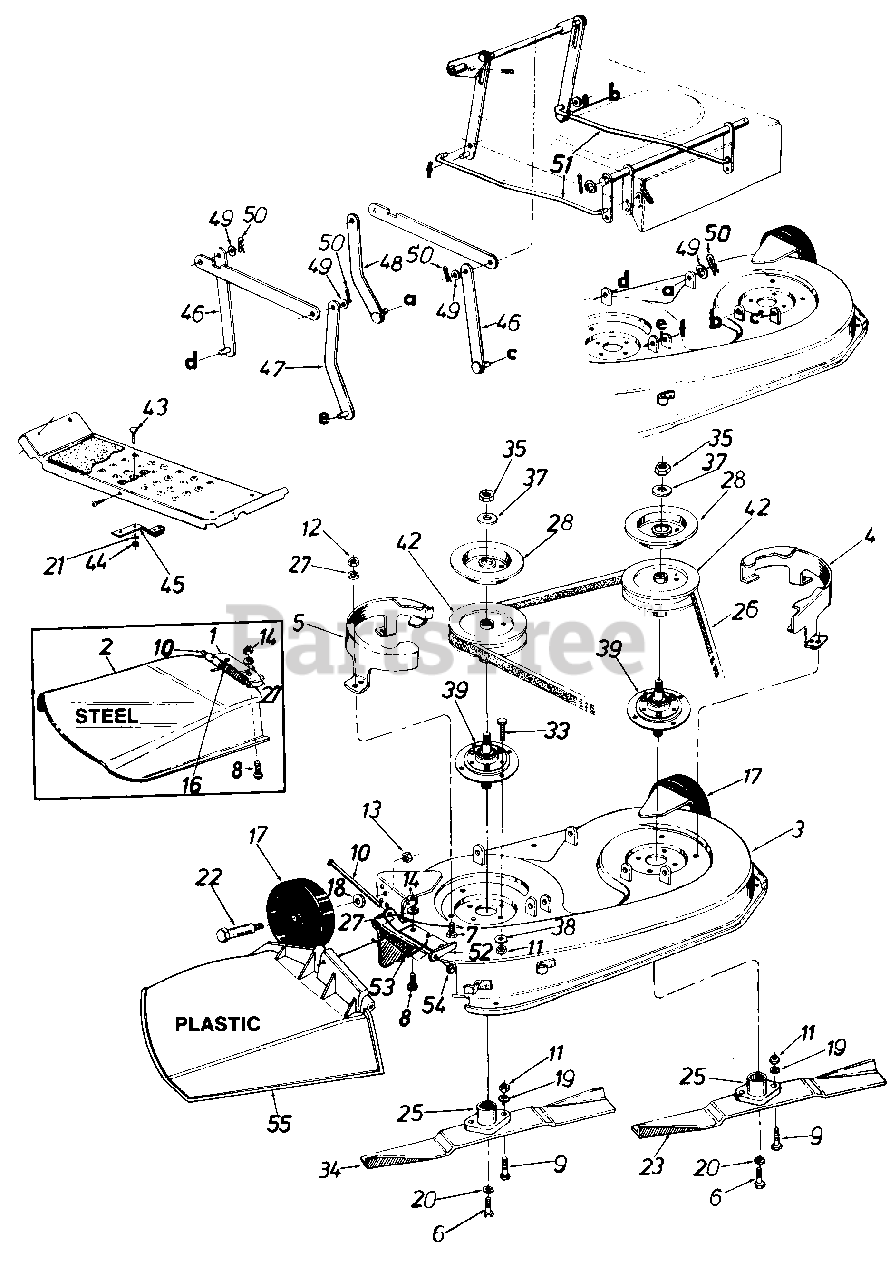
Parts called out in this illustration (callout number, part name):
1	Chute Bracket (Steel)
2	Chute Deflector (Steel)
3	38" Deep Deck Ass'y.
7	Hex Bolt 1/4-28 x .62"
8	Truss Mach. Scr. 1/4-20 x .75"
9	Hex Bolt Special 5/16-24 x 1.0"
10	Hinge Pin
11	Hex Nut 5/16-24 Thd.
12	Hex Nut 1/4-28 Thd.
13	Hex Top L-Nut 3/8-16 Thd.
14	Hex Jam Nut 1/4-20 Thd.
16	Torsion Spring
17	Deck Wheel 5"
18	Bell-Wash. .40" I.D. x .88" O.D.
19	L-Wash. 5/16" I.D.
20	L-Wash. 3/8" I.D. H.D.
21	L-Wash. 1/4" I.D.
22	Shld. Bolt .498" Dia. x 1.53"
23	High-Lift Blade L.H.
25	Blade Adapter
26	5L V-Belt
27	Bell-Wash. 1/4" I.D.
28	Brake Disc
33	Rib Neck Bolt 5/16-24 x 1.05" Lg.
34	High-Lift Blade R.H.
35	Hex Jam Nut 5/8-18 Thd.
37	L-Wash. 518" I.D.
38	L-Wash. 5/16" I.D.
39	Blade Spindle Ass'y. Comp.
42	51" Dia. Pulley
43	Carr. Bolt 1/4-20 x .62
44	Hex Nut 1/4-20 Thd
45	Blade Brake Ass'y.
46	Link Deck Hanger Ass'y.
47	Link Deck Hanger Ass'y.
50	Inter. Cotter Pin .501 Dia.
51	Stabilizer Rod
52	Hinge Mtg. Brkt.
53	Torsion Spring
54	Push Nut
55	Chute Ass'y. Comp. (Plastic)
